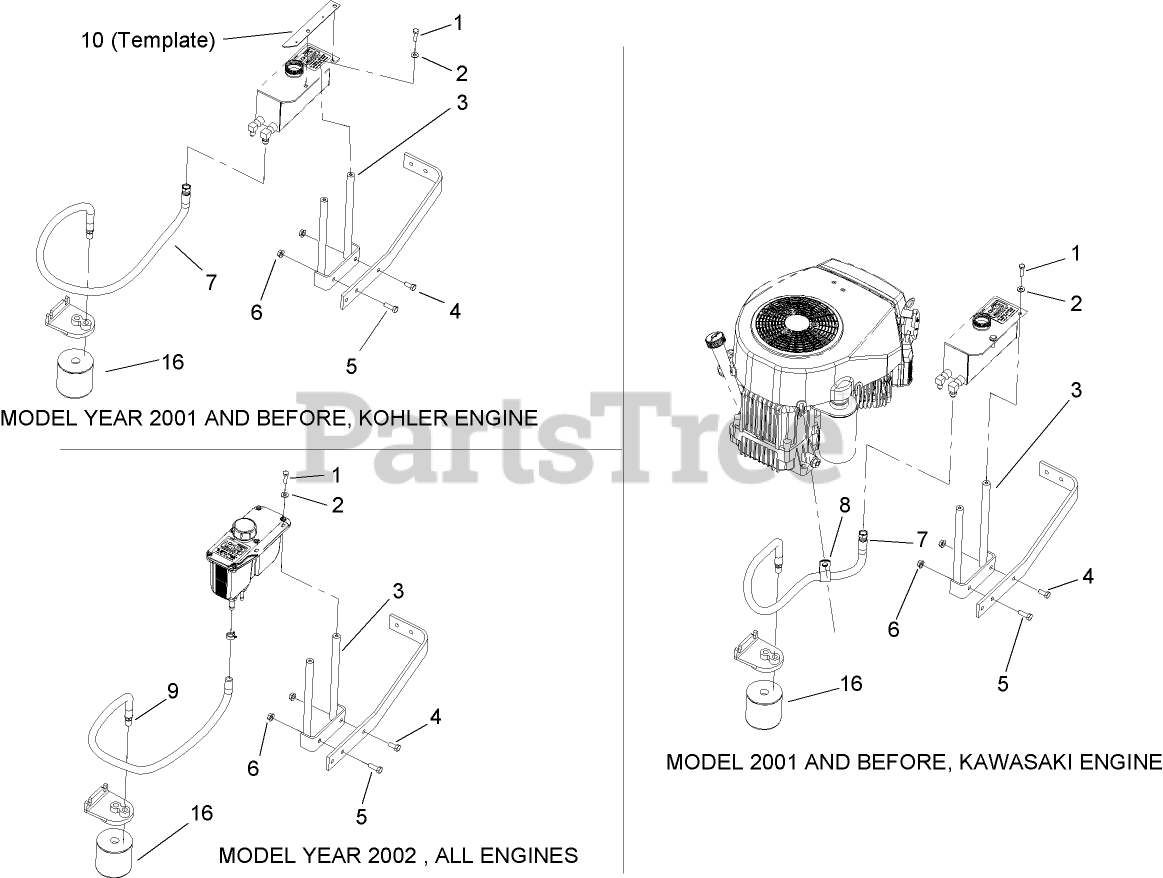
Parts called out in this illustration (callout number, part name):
1	SCREW-HH
2	WASHER-FLAT
3	STAND-RESERVOIR
4	SCREW-HH
5	SCREW-HH
6	NUT-HF
7	HOSE ASM
8	CLAMP-R
9	HOSE ASM
10	TEMPLATE-TANK, HYD
16	FILTER-OIL, HYD
